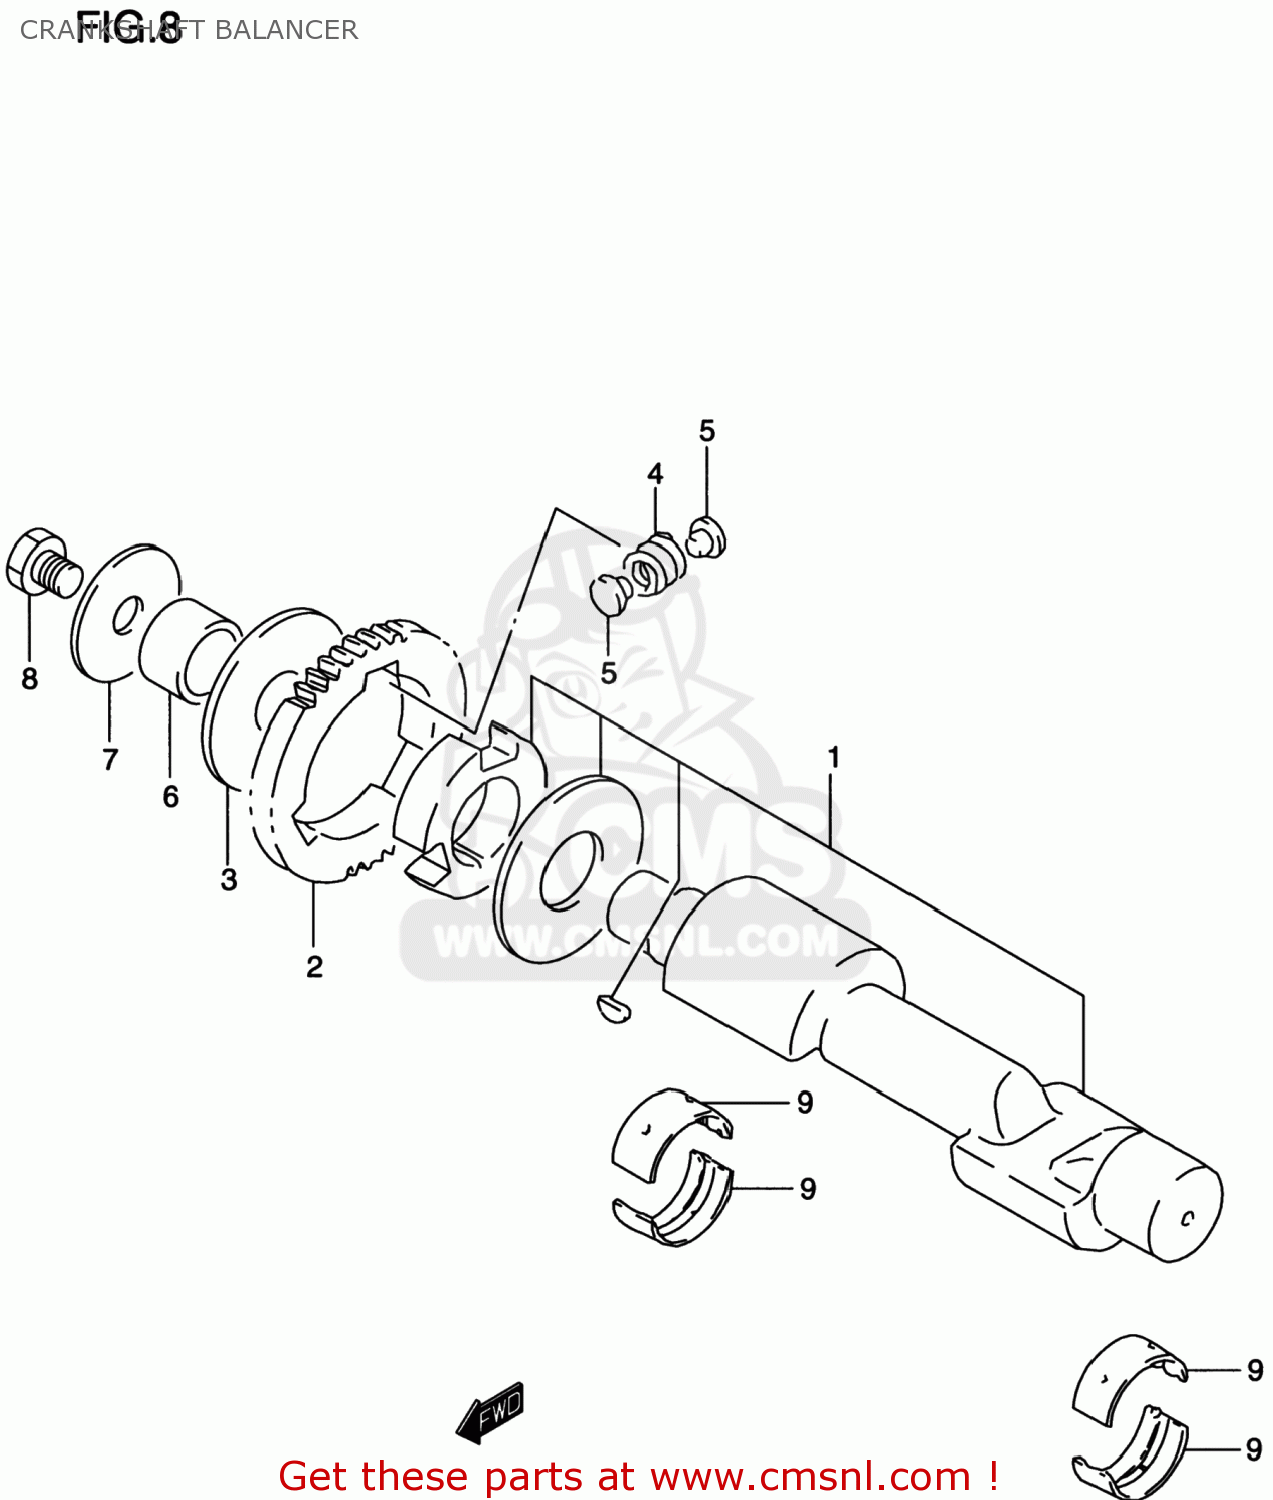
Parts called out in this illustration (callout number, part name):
1	BALANCER,CRANK
2	GEAR,CRANK BALANCER DRIVE
3	WASHER(24X70X3)
4	SPRING
5	PIN
6	SPACER(24X30.5X12.5)
7	WASHER(12X50X3)
8	BOLT
9	BEARING,CRANKSHAFT(GREEN)
